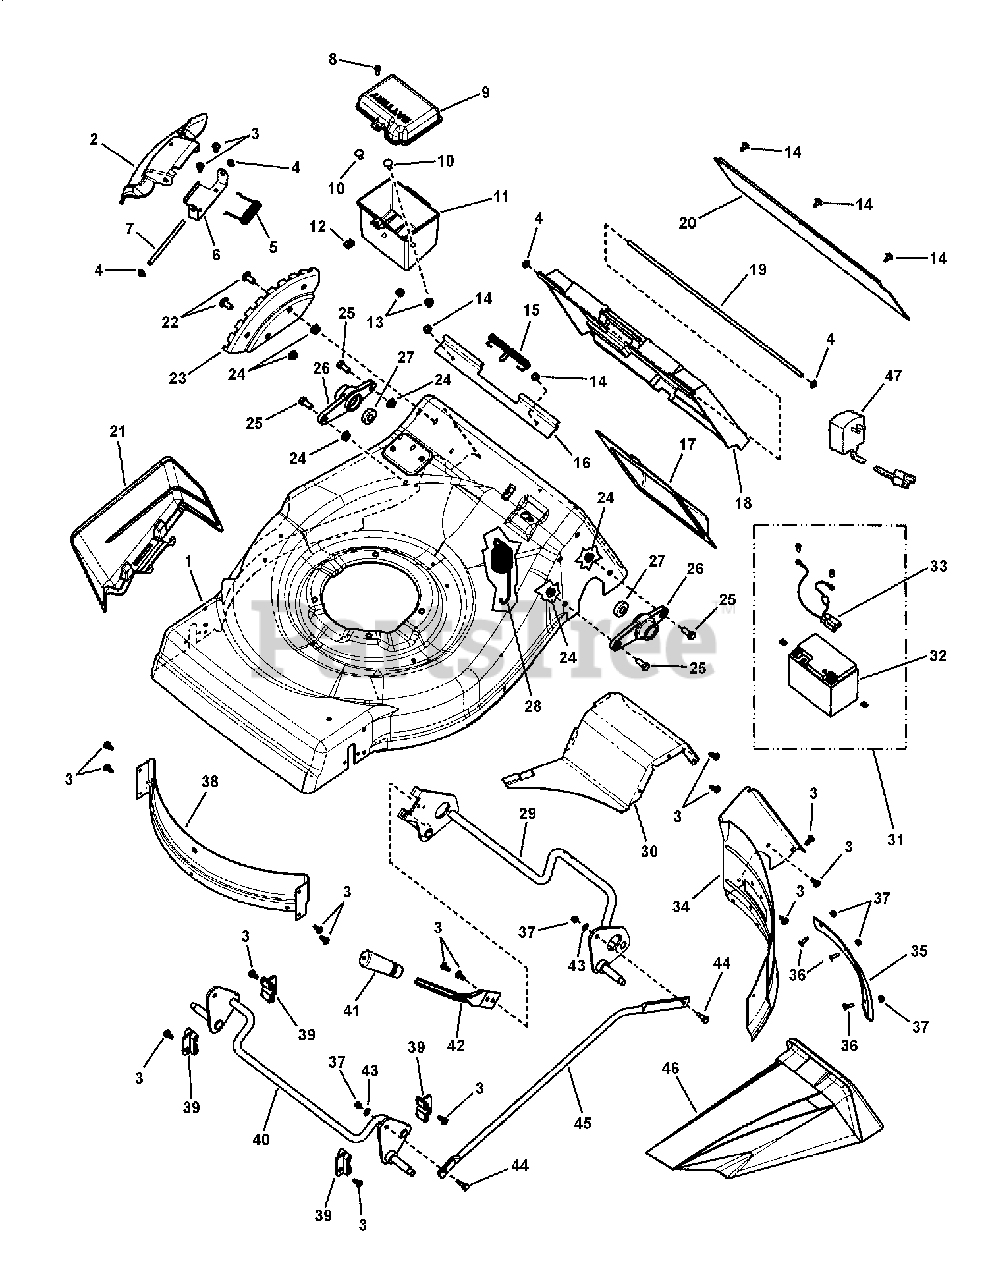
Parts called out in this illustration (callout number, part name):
1	DECK, 21" Rear Discharge, Non-Electric Start
1	DECK, 21" Rear Discharge, Electric Start
2	COVER, 21" Mulching
3	SCREW, 1/4-20 x .550 Pan Head Torx, Self-Tap
4	PUSHNUT, 1/4"
5	SPRING, 21 Coils, Chute Torsion
6	BRACKET, Chute Deflector
7	ROD, 4.69", .25 Dia., Pivot, Mulch Cover, Zinc/Clear
8	SCREW, #10-24 x 5/8" Hex Washer Face Self-Tap
9	TOP, Battery Box - 21" WBM
10	BOLT, 1/4-20 x 5/8" Flat Head Square Neck, GR 5
11	BOTTOM, Battery Box - 21" WBM
12	NUT, #10C Retainer Speed w/extrusion
13	NUT, 1/4-20 Hex Flange Whizlock
14	SCREW, #10-24 x 1/2" Hex Washer Self-Tap, SEMS
15	SPRING, 3.65" Long, 38 Coils, Torsion
16	SPACER, Rear Door, 21"
17	TRANSMISSION COVER, Rear 21"
18	DOOR, 21" Black
19	ROD, 17.88", .25" Dia., Pivot, Rear Door, 21 RD
20	DEFLECTOR, Rear, 21" WBM, RD
21	CHUTE, 21" Side Discharge
22	BOLT, 5/16-18 x 3/4" Round Head Short Square Neck, GR 5, YZ
23	INDEX PLATE, Height-of-Cut, 21" WBM, RD
24	NUT, 5/16-18, Serrated Lock Flange, GR5
25	SCREW, 5/16-18 x 3/4" Hex Head Cap, GR 5 YZ
26	BEARING HOLDER, 21" WBM,RD
27	BEARING, 1.125" OD, .5" ID, .3125" Wide, Ball
28	SPRING, 6.25", 11 Coils, 90° Offset Hooks, HOC Assist
29	WELDMENT, Rear Crossbar 21" WBM, RD, YZ
30	BAFFLE, Right Rear, 21" WBM, RD
31	BATTERY KIT, 12V, 4.0 AH (incl. harness 7015488)
32	BATTERY, Sealed Lead Acid, 12V (Use Battery Kit)
33	HARNESS, Battery
34	BAFFLE, Left Rear, 21" RD, WBM
35	BAFFLE, Extension, 21" RD WBM
36	BOLT, #10-24 x 5/8" Flat Head Square Neck, YZ
37	NUT, #10-24 Hex Nyloc
38	BAFFLE, Front 21" WBM, RD
39	BUSHING, Front, 21"
40	WELDMENT, Front Crossbar 21" WBM, RD, YZ
41	GRIP, Height-of-Cut
42	LEVER, Spring Height-of-Cut
43	PUSHNUT, 1/4 Black
44	BOLT, Shoulder, #10-24 Thread
45	ROD, Lifter Link
46	PLUG, Mulching
47	KIT, Battery Charger 120V/12V
